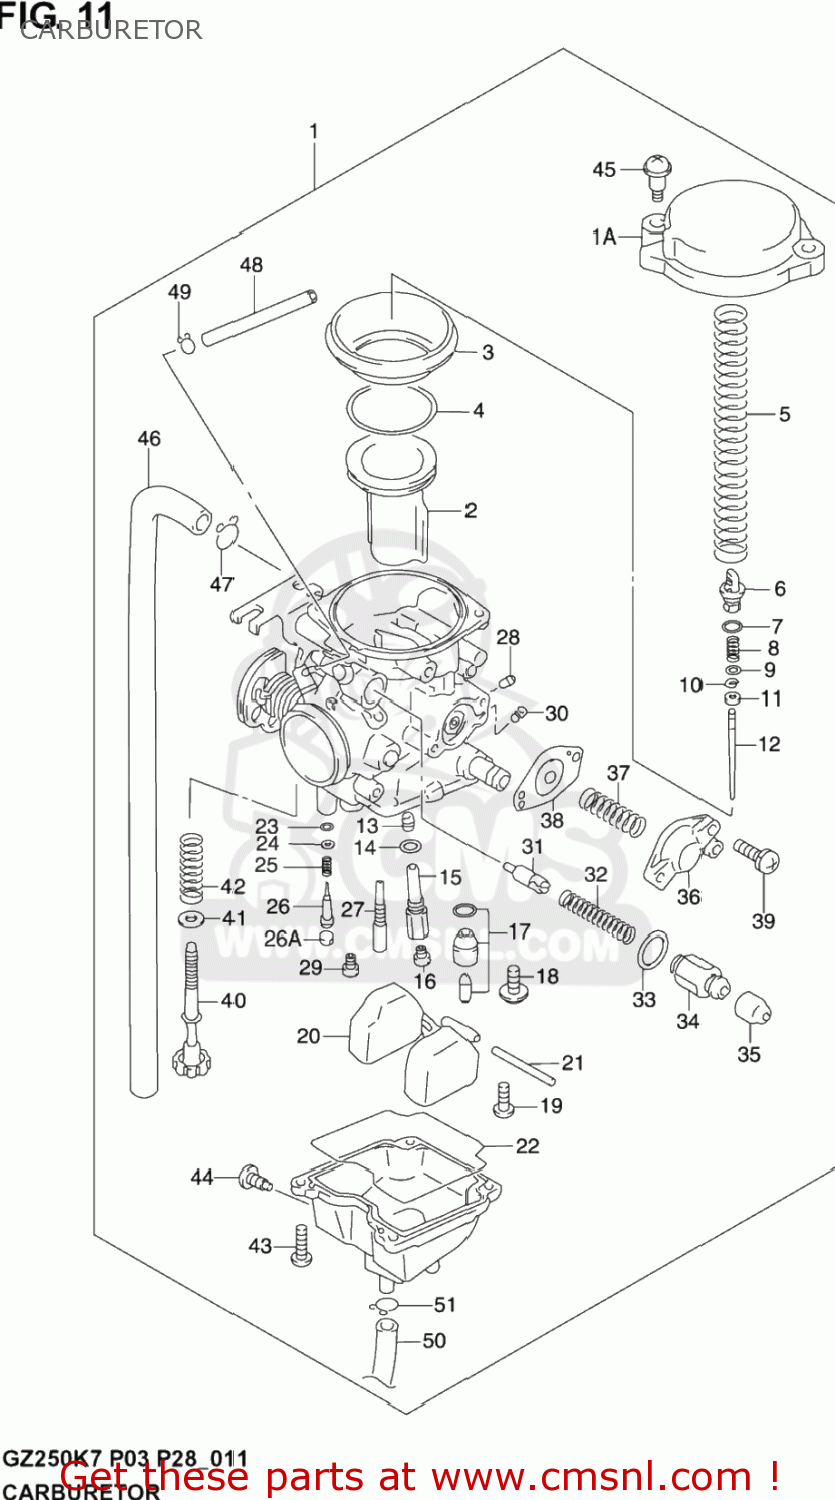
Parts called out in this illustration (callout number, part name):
1	CARBURETOR ASSY
1A	COVER,DIAPHRAGM
2	VALVE,PISTON
3	DIAPHRAGM
4	RING
5	SPRING
6	HOLDER
7	O RING(D:1.9,ID:4.8)
8	SPRING
9	WASHER
10	E RING,MULTIPLE JET NOZZLE
11	RING
12	NEEDLE,JET
13	JET,NEEDLE(P-0M)
14	O RING
15	HOLDER,JET
16	JET,MAIN(120)
17	VALVE ASSY,NEEDLE
18	SCREW
19	SCREW
20	FLOAT ASSY
21	PIN,FLOAT
22	GASKET (NAS)
23	O RING,PILOT AIR SCREW
24	WASHER
25	SPRING,THROTTLE SCREW
26	ADJUSTER
26A	PLUG
27	JET,PILOT(17.5)
28	JET,MAIN(87.5)
29	JET,MAIN(52.5)
30	JET,PILOT AIR(120)
31	PLUNGER
32	SPRING
33	O RING
34	HOLDER,GUIDE
35	CAP
36	COVER ASSY
37	SPRING
38	DIAPHRAGM ASSY
39	SCREW
40	SCREW,ADJUST
41	PACKING (NAS)
42	SPRING
43	SCREW
44	SCREW,DRAIN
45	SCREW
46	HOSE
47	CLIP
48	HOSE
49	CLIP
50	HOSE(4.5X8X650)
51	CLIP
